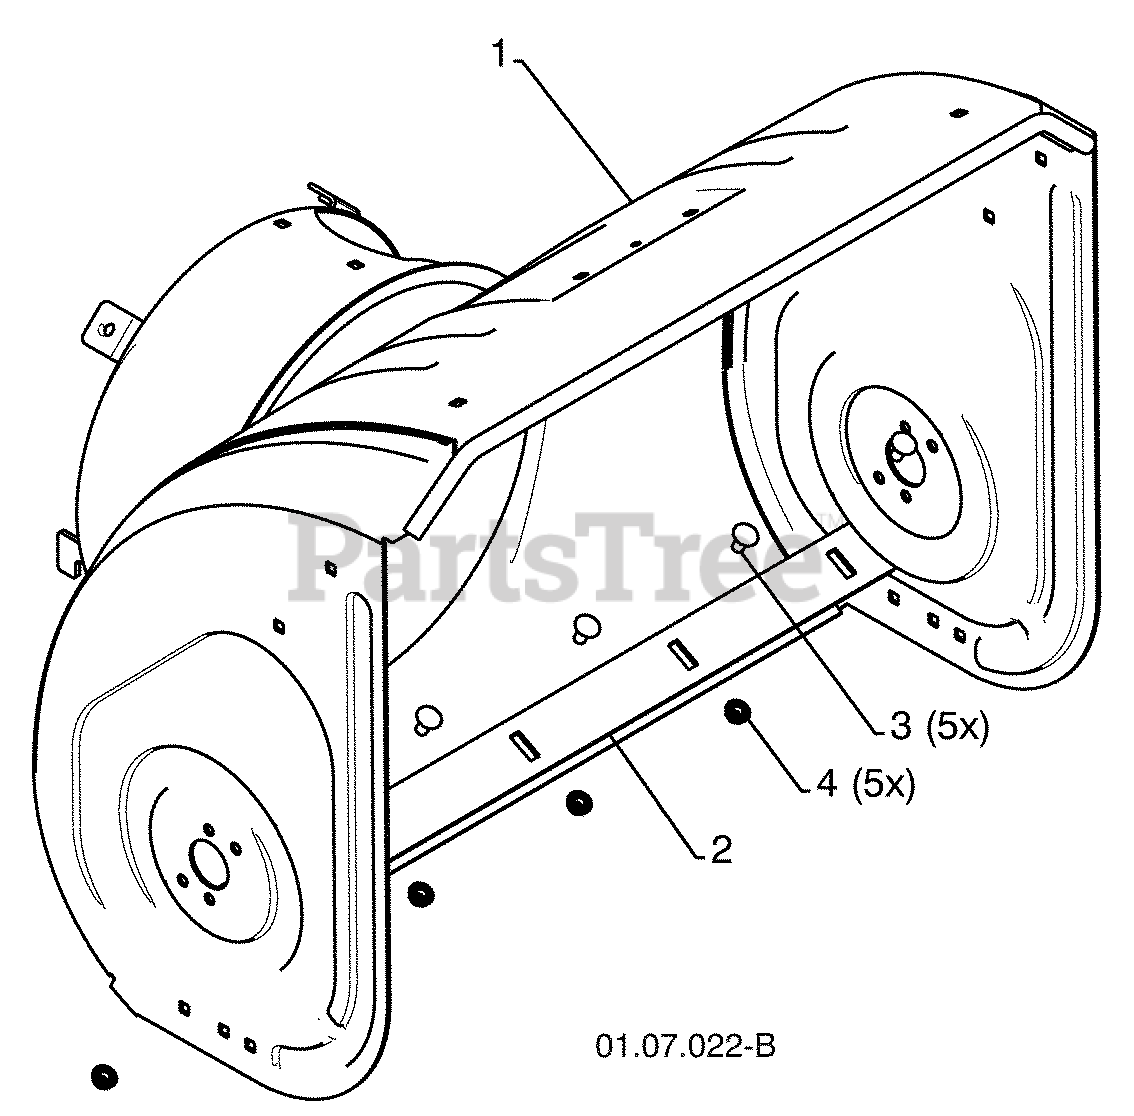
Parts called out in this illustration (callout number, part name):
1	RP HOUSING.AUG.WELDMENT
2	BAR, SCRAPER
3	BOLT
4	NUT.FLANGE.5/16
